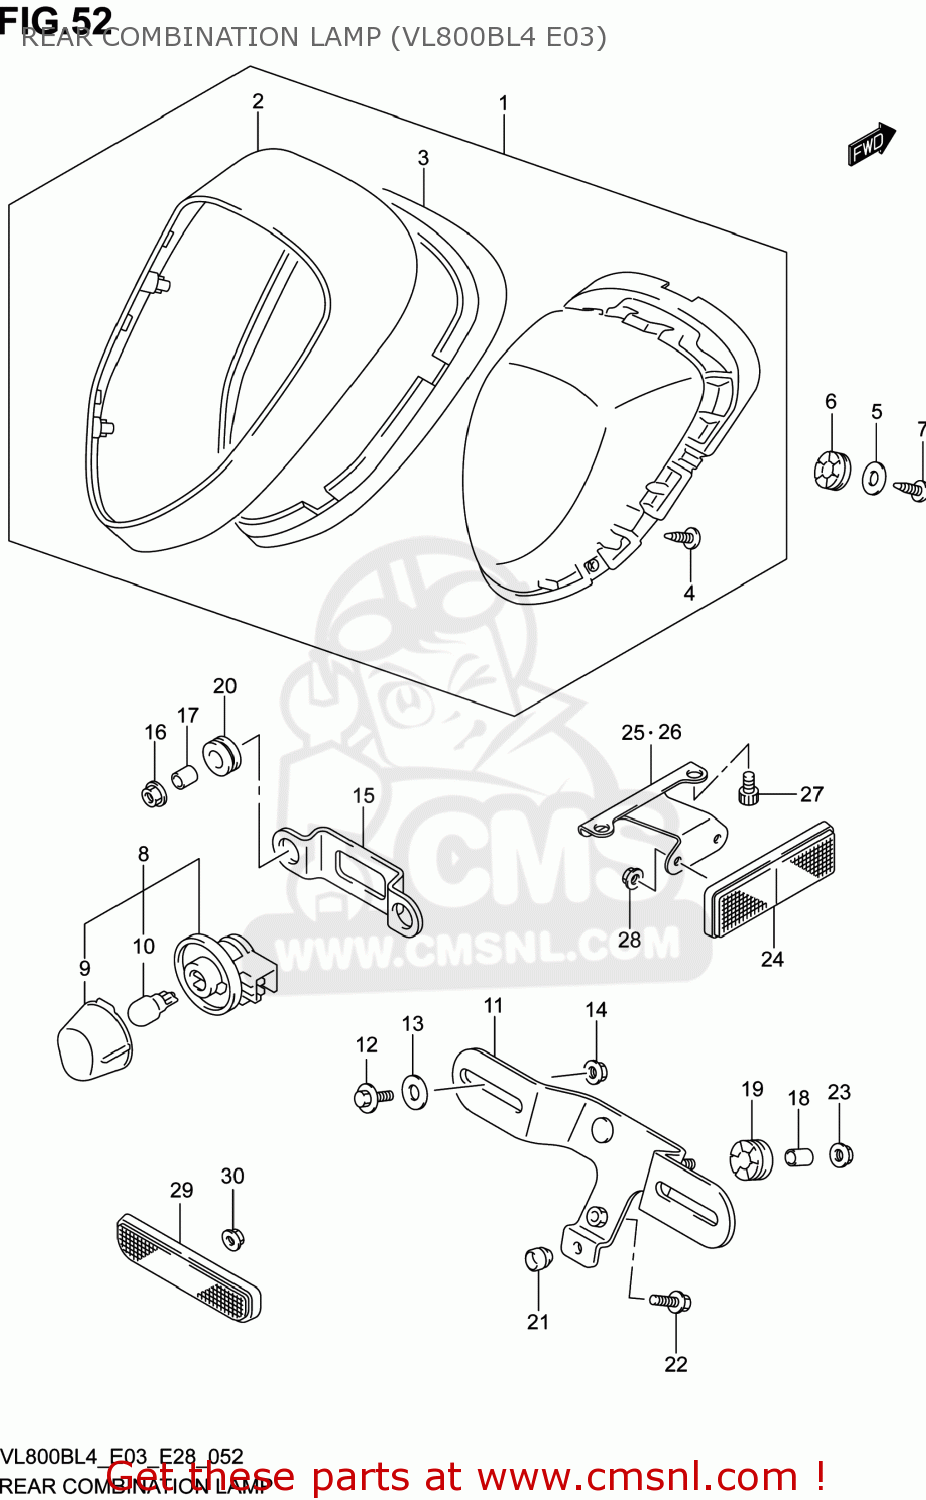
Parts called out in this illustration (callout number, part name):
1	LAMP ASSY,REAR COMB
2	COVER
3	RUBBER
4	SCREW(3X12)
5	WASHER(5.5X20X1.2)
6	CUSHION,RR COMBINATION
7	SCREW
8	LAMP ASSY,LICENSE
9	LENS
10	BULB(12V5W)
11	BRACKET,LICENSE PLATE
12	BOLT(6X16)
13	WASHER(6.5X20X1.2)
14	NUT
15	BRACKET,LICENSE LAMP
16	NUT
17	SPACER(5.5X9.5X11.5)
18	SPACER(6.5X10X12)
19	CUSHION
20	CUSHION
21	CUSHION
22	BOLT
23	NUT
24	REFLECTOR ASSY,RR
25	BRACKET,RR SIDE RR,R
26	BRACKET,RR SIDE RR,L
27	BOLT
28	NUT
29	REFLECTOR ASSY,RR
30	NUT
